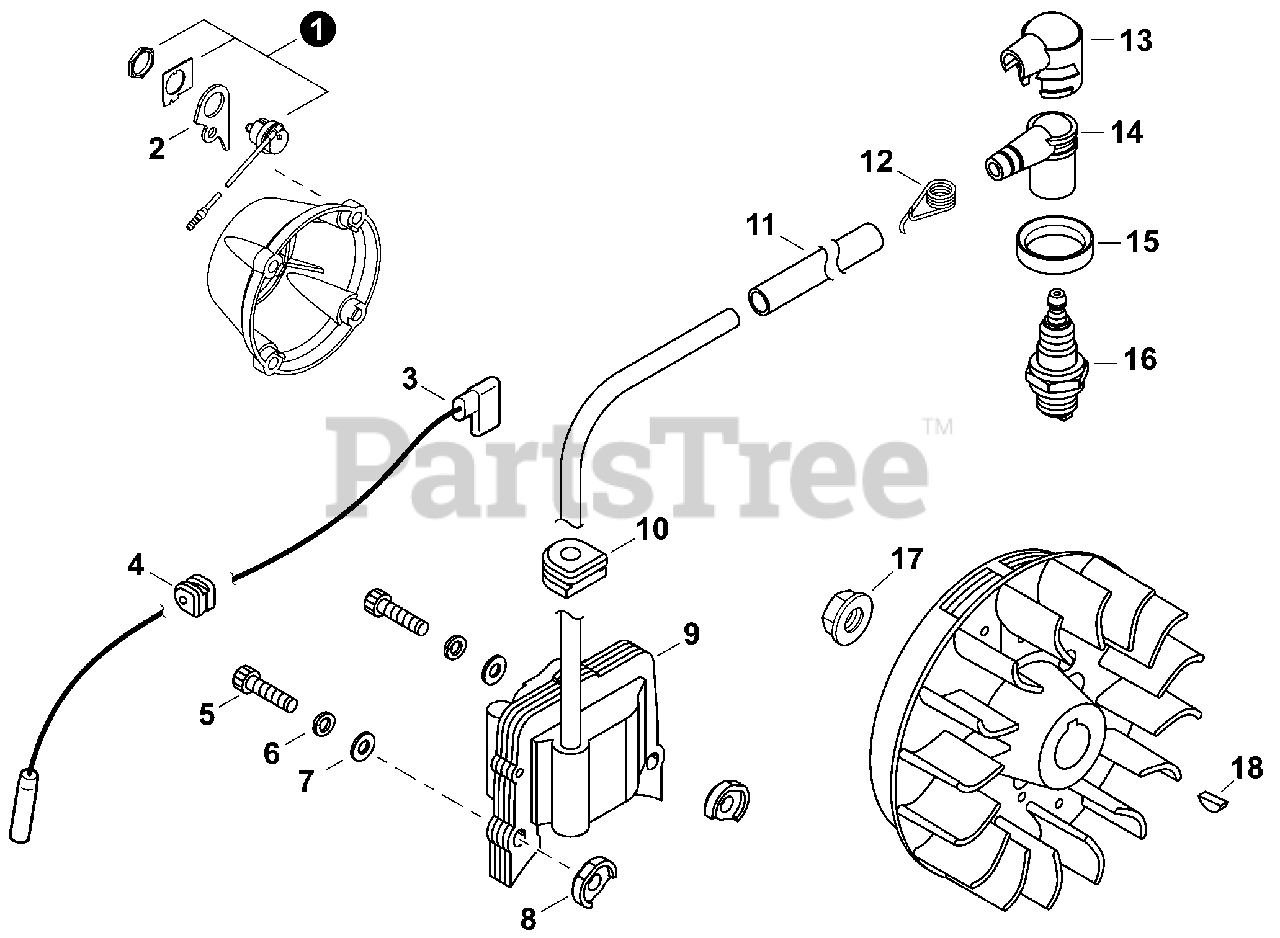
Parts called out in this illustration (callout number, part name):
1	SWITCH, ON-OFF
2	BRACKET
3	LEAD - IGNITION
4	GROMMET, LEAD
5	BOLT M4×24
6	WASHER, SPRING 4mm
7	WASHER 4.3×9.6×0.8
8	COLLAR 4
9	COIL, IGNITION
10	GROMMET
11	TUBE, INSULATOR
12	TERMINAL, SPARK PLUG
13	COVER, CAP
14	CAP, SPARK PLUG
15	SEAL, SPARK PLUG
16	SPARK PLUG - CJ8
17	NUT, FLANGE M10
18	KEY, WOODRUFF 3×10
